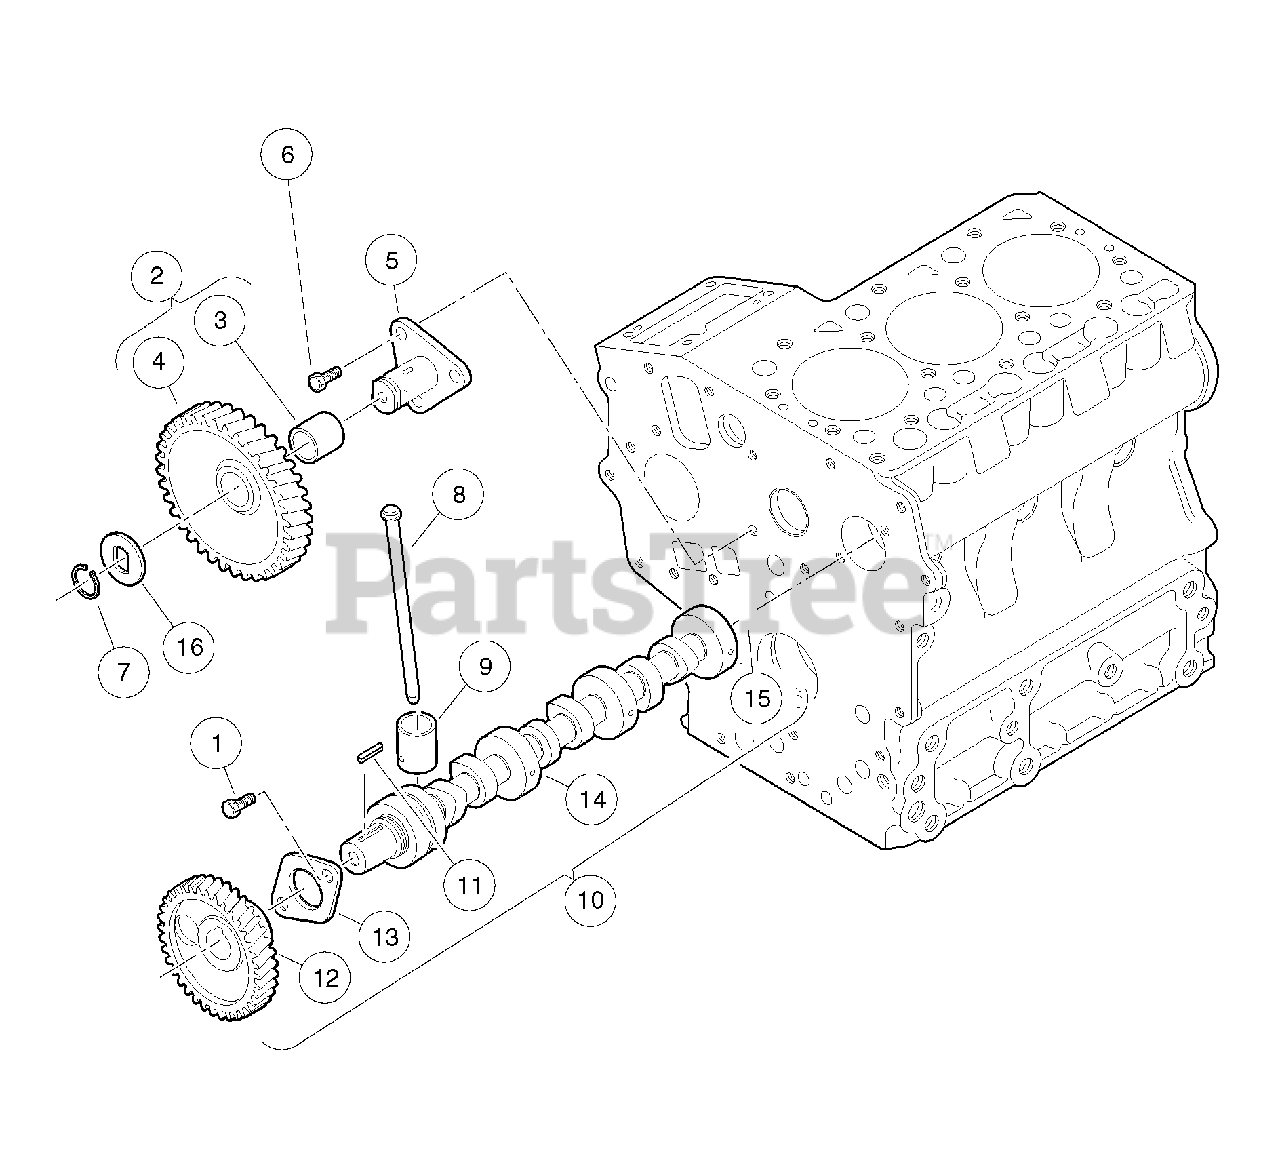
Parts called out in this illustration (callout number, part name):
1	Bolt, D722, Cam End
2	Gear, Idle
3	Bushing, D722 Idle Gear
4	Gear, Idle
5	Shaft, Idle Gear
6	Bolt, M6 X 1 X 14
7	Ring, Snap
10	Assy Camshaft, Long
11	Key, Feather, Long Camshaft
13	Stopper, Camshaft
14	Camshaft
15	Ball, Check
16	Collar, Idle Gear
